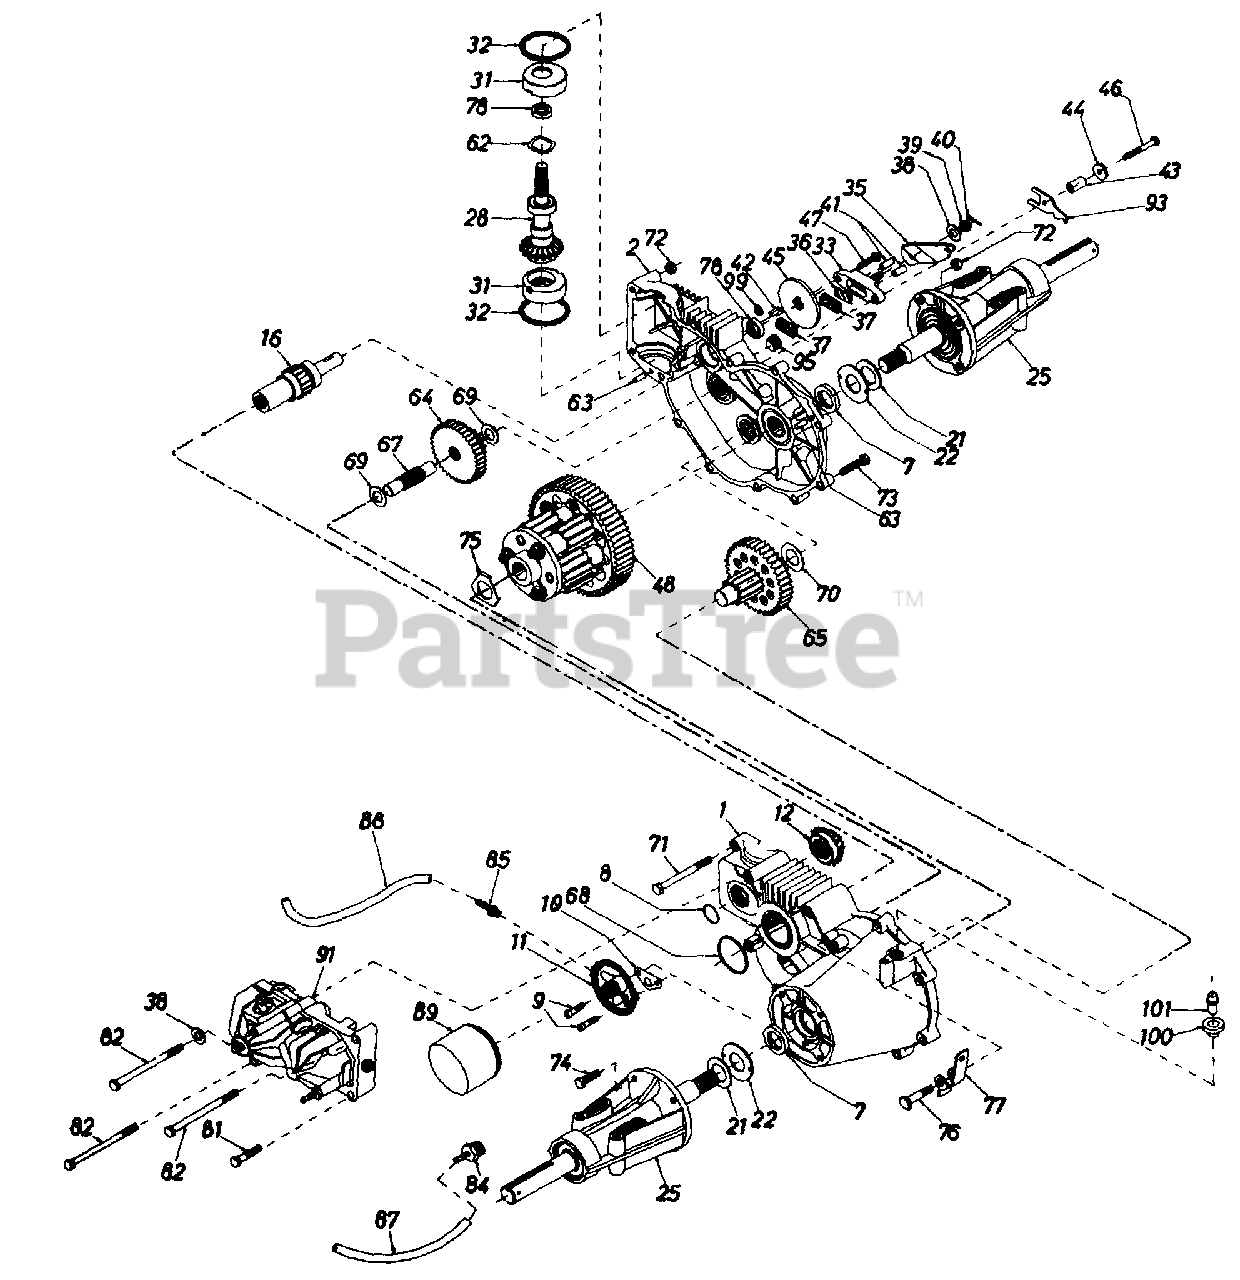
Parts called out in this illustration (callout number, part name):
1	Housing - L.H. Ass'y.
2	Housing - R.H. Ass'y.
7	Oil Seal .984" x 1.5" x .25"
8	Quad Ring
10	Filter Base Gasket
11	Filter Base Ass'y.
12	Pinion Ass'y.
16	Brake Shaft Ass'y.
21	Washer, 1.0" x 1.63" x .08"
22	Washer, 1.0" x 2.06" x .09"
25	Axle Mounting Horn Ass'y.
28	Input Ass'y.
31	Ret. Bearing
32	O-Ring 2-1/2" O.D.
33	(Sub) Brake Yoke Ass'y.
35	Brake Arm
36	Puck Plate
37	Brake Puck
38	Washer, 7/16" x 7/8" O.D. x .060 H.T.
39	Nut, Castle 5/16-24 PL
40	Cotter Pin
41	Brake Actuating Pin
42	Hi-Pro Key 3/16" x 5/8"
43	Torsion Spring Spacer
44	Washer 7/8 O.D. x .260 I.D. x 1/8
45	Disc Brake
46	Bolt 1/4-20" x 2 W/Nylok Gr. 5
47	Bolt 1/4-20" x 1 W/Nylok Gr. 5
48	Differential Ass'y.
62	Wave Washer
63	Dowel Pin
64	Reduction Gear 14T-38T
65	Final Drive Pinion Ass'y.
67	Jack Shaft
68	O-Ring
69	Fl-Wash. 5/8" I.D. x 1-5/32" O.D. Ht.
70	Fl-Wash. 7/8" I.D. x 1-1/2" O.D. Ht.
71	Hex Bolt H.D. 5/16-18" x 3-1/2"
72	Hex Lock Nut 5/16-18" 2-Way Plt.
73	Hex Bolt 5/16-18" x 1-1/2" Gr. 5 Plt.
74	Hex Bolt 5/16-18" x 1
75	Differential Washer .050
76	Shld. Bolt
77	Freewheel Actuating Arm
78	Oil Seal .625" x 1.0" x .25"
81	Hex Bolt 5/16-18" x 1-3/4"
82	Hex Bolt 5/16-18" x 4-1/2"
84	SAE Port Straight Fitting 7/8"
85	SAE Port Straight Fitting 7/16"
87	Hose, 8-1/2" Long
88	Hose 10-1/2" Long
89	Spin-On Filter
91	Transmission
93	Bracket
95	Straight Thread Plug
99	Washer 5/16" I.D. x 9/16" O.D.
100	Vent Bushing
